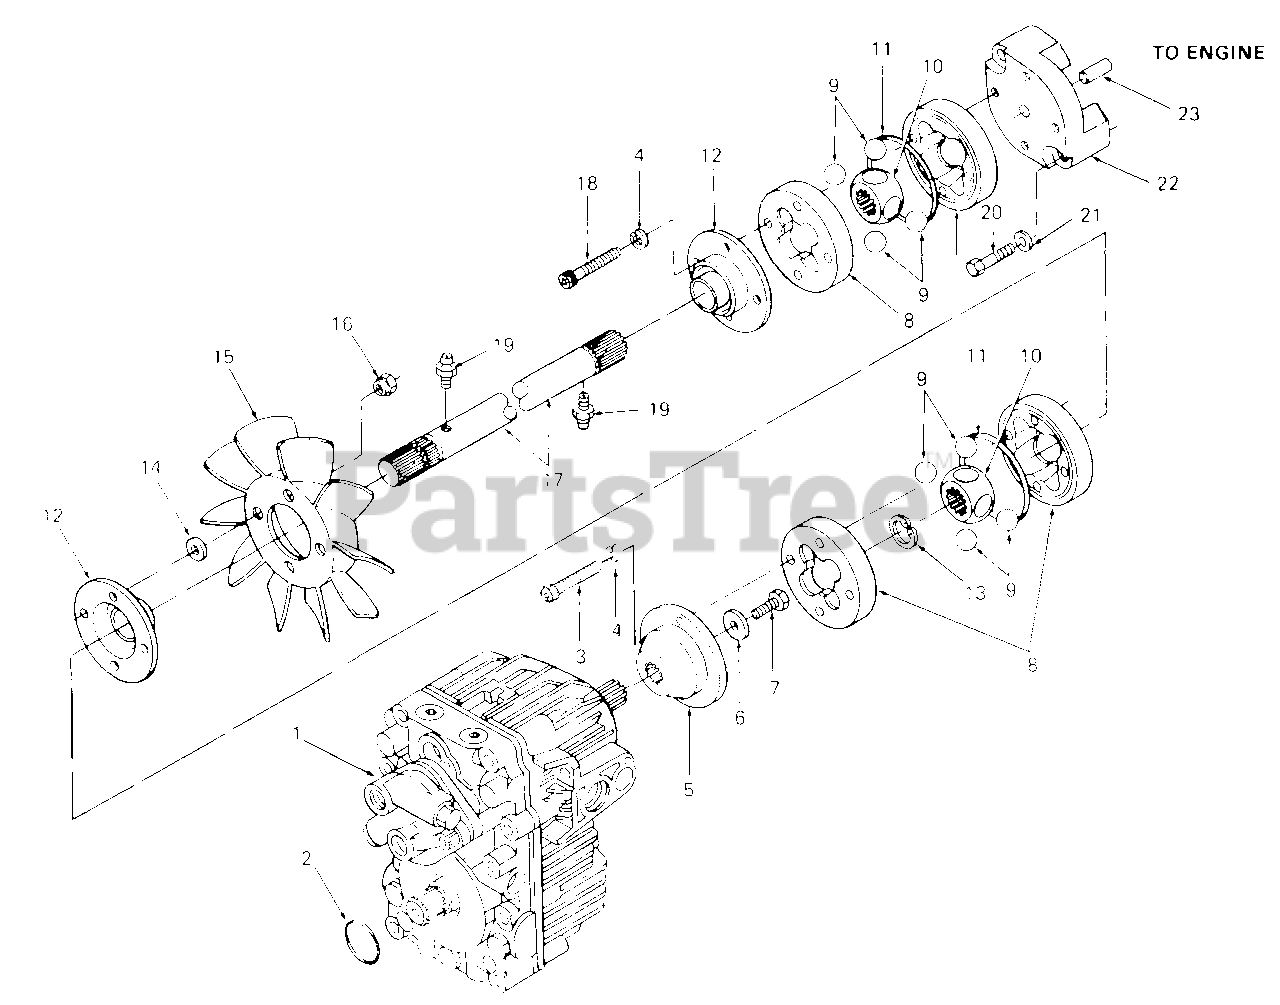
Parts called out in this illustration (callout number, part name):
1	Pump, Hydrostatic
2	O-Ring, 2.75 ID X .103 Dia
3	Screw, Socket Hd Cap, 1/4-20 X 2.0 Lg
4	Washer, Lock, 1/4
5	Adapter, Pump
6	Washer, Bell, .265 X .75 X .062 Thk
7	Bolt, Hex Patch, M6-1.0 X 20 MM Lg GR10.9
8	Coupling, Drive w/0-Ring Groove
9	Ball, Steel, 5/8 Dia Chrome
10	Hub, Drive
11	O-Ring, 2.489 X .070
12	Boot, Coupling
13	Ring, Snap
14	Washer, Flat, .25 X .62 X .052 Thk
15	Fan, 10 Blade Hydro
16	Nut, Fan, 1/4-20
17	Shaft, Drive, 21.3 Lg
18	Screw, Socket Hd Cap, 1/4-20 X 1.75 Lg
19	Fitting, Grease
20	Screw, Hex Cap, 5/16-18 X 1.75 Lg GR5
21	Washer, Flat, .312 X .750 X .119 Thk
22	Adapter, Drive Shaft
23	Pin, Locating
